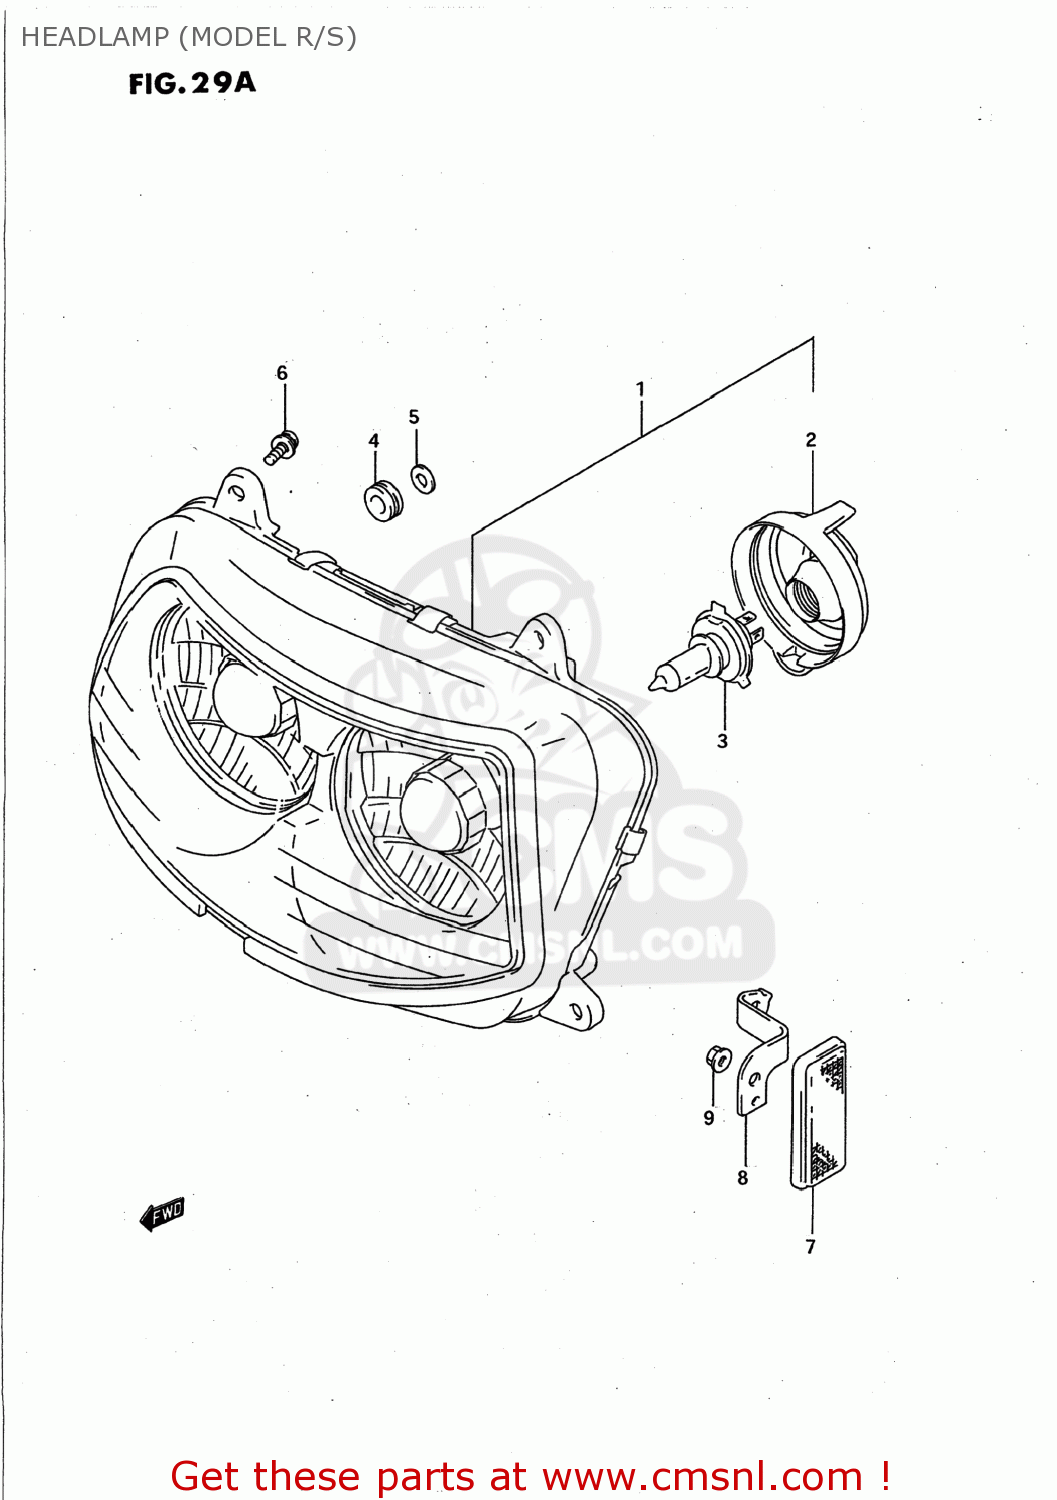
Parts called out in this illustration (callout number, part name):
1	HEADLAMP ASSEMBLY
2	COVER,SOCKET
3	BULB(12V60/55W,H4)
4	CUSHION
5	WASHER(5.5X16X1.2)
6	SCREW,SIDE HOL
7	REFLEX REFLECTOR,FR SIDE
8	BRACKET,FR SIDE RR,R
9	NUT
